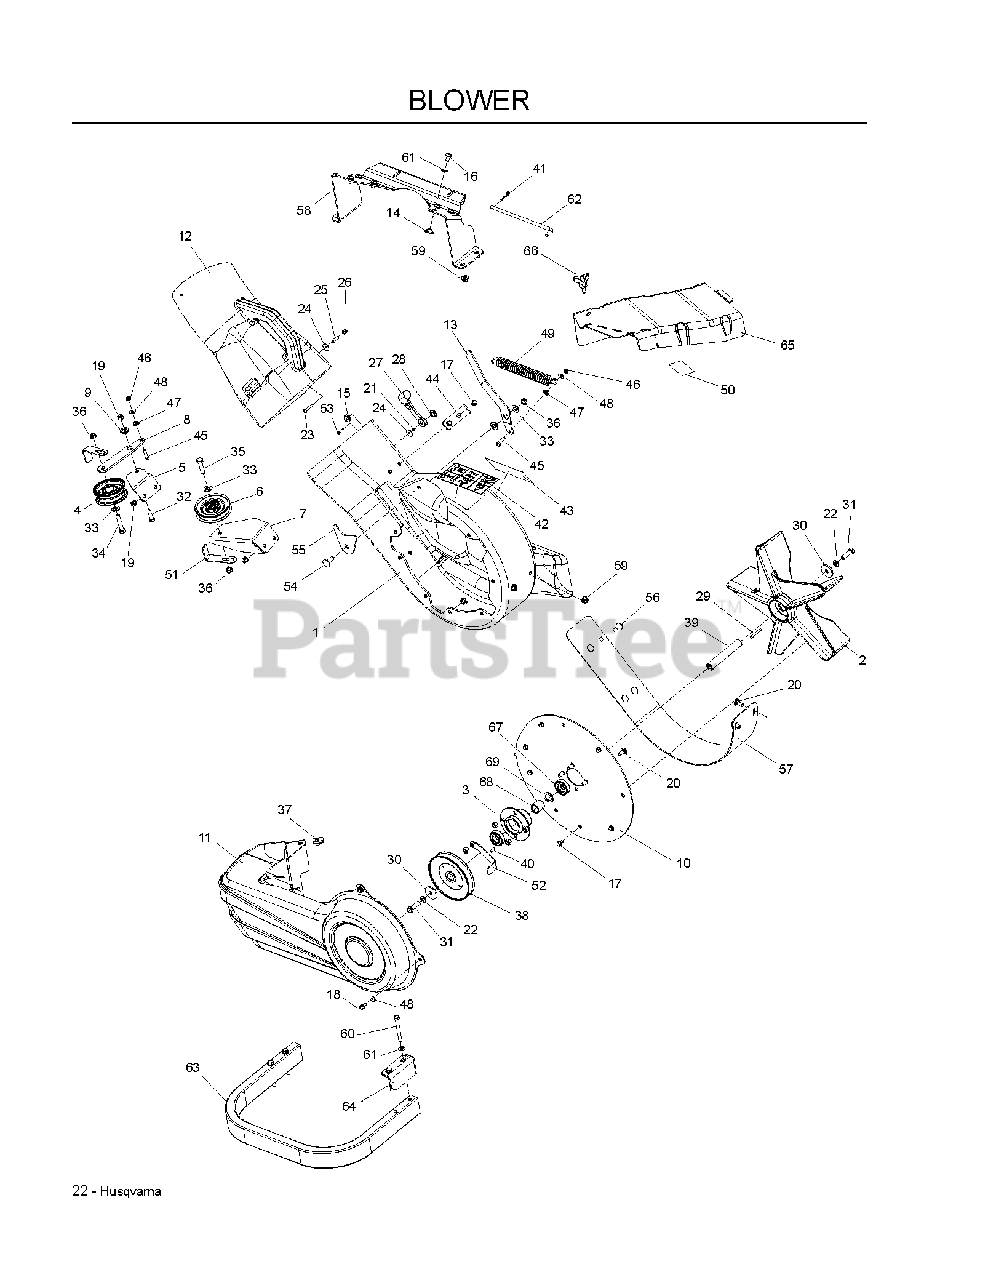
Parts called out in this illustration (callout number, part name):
1	HOUSING W/DECALS
2	IMPELLER
3	HUB, BEARING
4	IDLER PULLEY
5	MOUNT, IDLER, UPPER
6	V-IDLER
7	MOUNT, IDLER, LOWER
8	ARM, IDLER
9	BUSHING
10	PLATE, OUTER
11	COVER, BELT
12	CHUTE, MIDDLE
13	ARM, TENSION
14	NUT 5/16-18 TEE
15	NUT 1/4-20 TEE
16	HCS 5/16-18 X 1/2 GR 5 ZD
17	HWST 1/4C X 3/8
18	BOLT 1/4-20 X 1/2 HWST
19	NUT 5/16 NYLOC
20	BOLT 5/16C X 3/4" CARRIAGE
21	WASHER - 3/16 LOCK ZD
22	SLW 3/8 STD
23	SCREW #10-24 X 1-1/8 ZD SPEC
25	BSHG .202X.75 LG SPLIT ZD SPEC
29	KEY-SQ. 3/16 X 1 1/2
30	WASHER, HARDENED
32	HCS 5/16C X 1
33	WASHER 3/8 SAE FLAT
34	BOLT, HCS 3/8-16X1-3/4
35	HCS 3/8C X 1 1/2
36	NUT HEX 3/8-16 NYLON, THIN
37	U-CLIP 5/16-18 NUT RETAINER
39	SHAFT, IMPELLER
40	KEY, 3/16 X 1/2
41	HAIRPIN #2
42	DECAL, EURO WARNING
43	EURO DECAL, IMPELLER
45	HCS 1/4-20X7/8 GR5
46	JAM NUT 1/4C
47	NUT 1/4-20 HEX FLG LK ZD
48	WASHER 1/4 SAE
50	DECAL, BELT ROUTING
51	KEEPER, BELT, REAR
52	KEEPER, BELT, OUTER
53	SCREW #10-24 X 5/8
54	RHSNB 3/8C X 1
55	PLATE, BACKING
56	RHSNB 5/16C X 1
57	LINER, SAND, BLK
58	BRACKET, MOUNT, BLK
59	5/16-18 NYLOC FLANGE NUT
60	HCS 5/16C X 2-3/4
61	FLAT WASHER 5/16 SAE
62	PIN, RETENTION
63	TUBE, RUB, BLK
64	BRACKET, RETENTION, BLK
65	COVER, BELT
66	KNOB W/STUD
67	BEARING
69	WASHER .787 X 1.125 X .06
